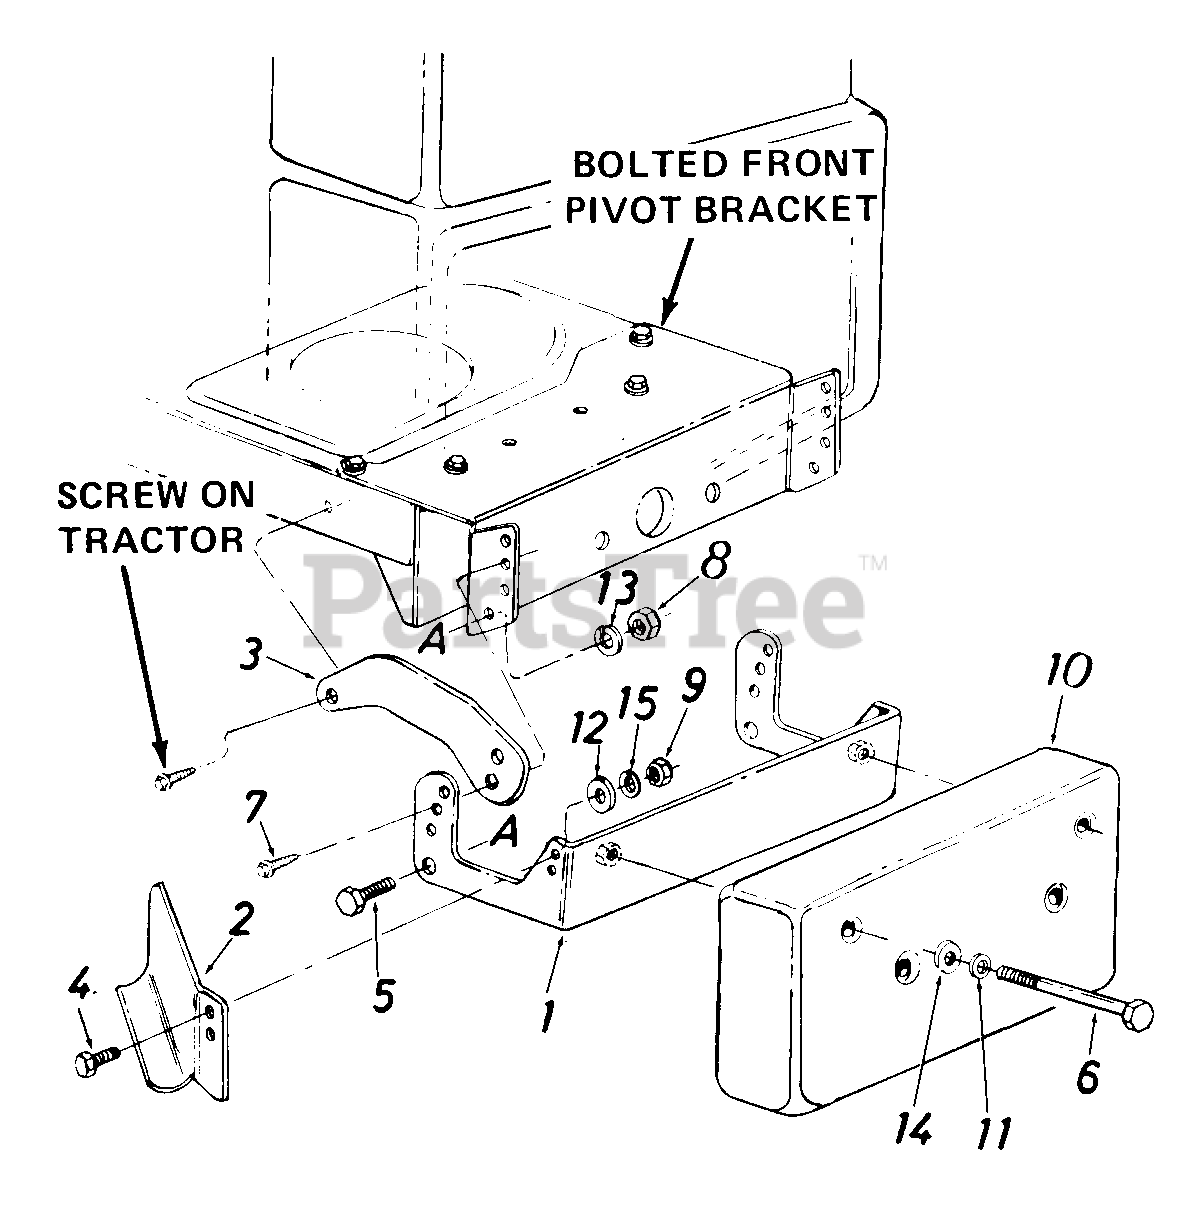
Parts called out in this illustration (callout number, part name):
1	Counterweight Bracket Ass'y.
2	Exhaust Deflector
3	Tie Strap
4	Hex Bolt 1/4-20 x .62" Lg.*
5	Hex Bolt 7/16-20 x 1.0" Lg.
6	Hex Bolt 3/8-16 x 4.5" Lg.
7	Hex AB Tap Scr. 5/16-18 x 1.0" Lg.
8	Hex Jam Nut 7/16-20 Thd.
9	Hex Nut 1/4-20 Thd.*
10	Front Counterweight-38 Lbs.
11	Bell-Wash. .40" I.D. x .88" O.D.
12	Fl-Wash. .28" I.D. x .50" O.D.
13	L-Wash. 7/16" I.D.
14	Fl-Wash. .39" I.D. x 1.12" O.D.
15	L-Wash. 1/4" I.D.*
